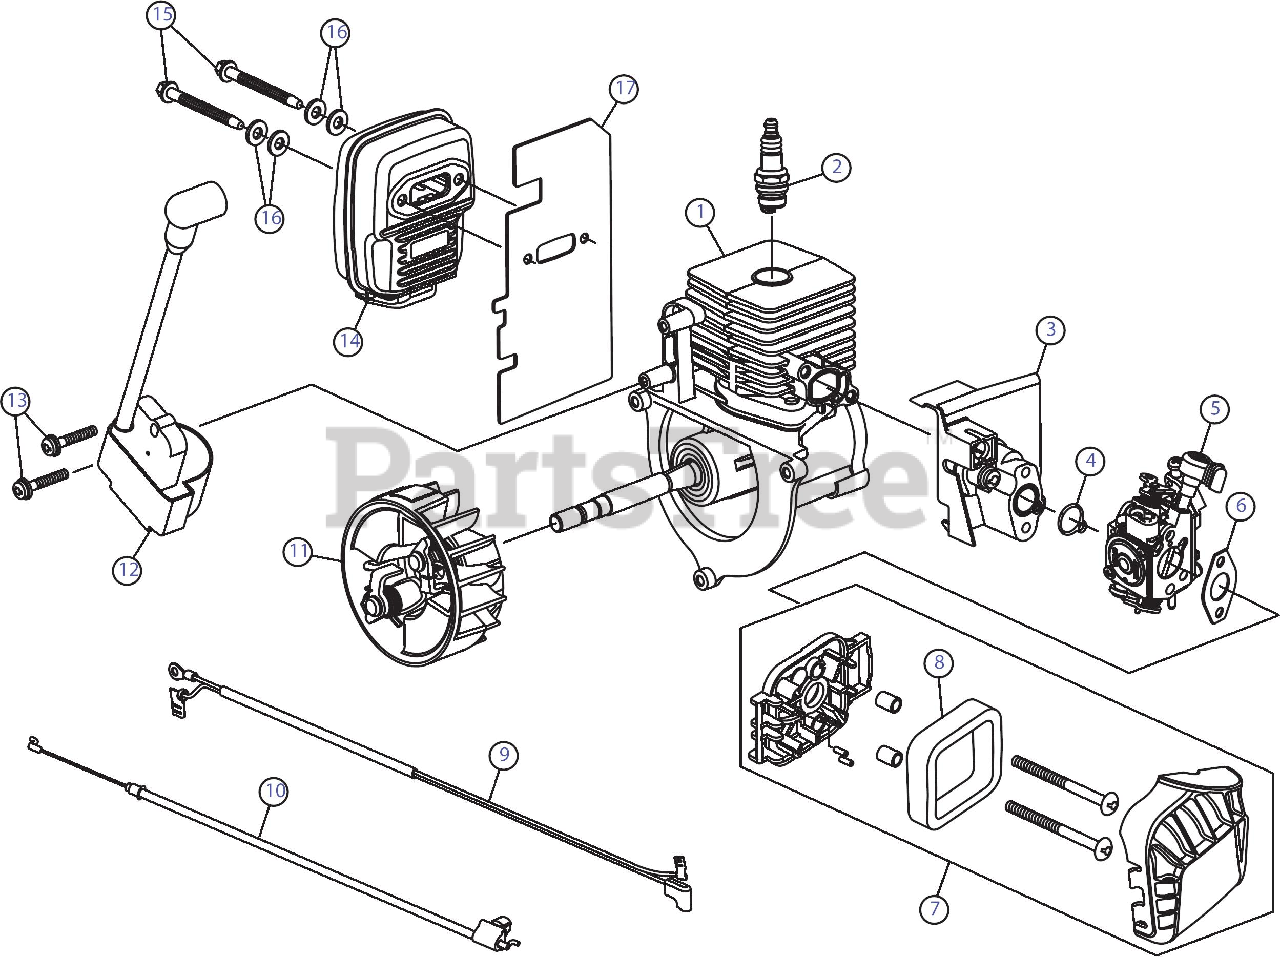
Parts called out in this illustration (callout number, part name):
1	Shortblock Assembly
2	Spark Plug
3	Insulator Assembly
4	O-Ring
5	Carburetor
6	Carburetor Gasket
7	Air Cleaner Assembly
8	Air Cleaner Filter
9	Lead Wire
10	Throttle Cable
11	Flywheel Assembly
12	Module Assembly
14	Muffler Assembly (Incl. 15, 16 and 17)
15	Muffler Screws
16	Washers
17	Muffler Gasket
